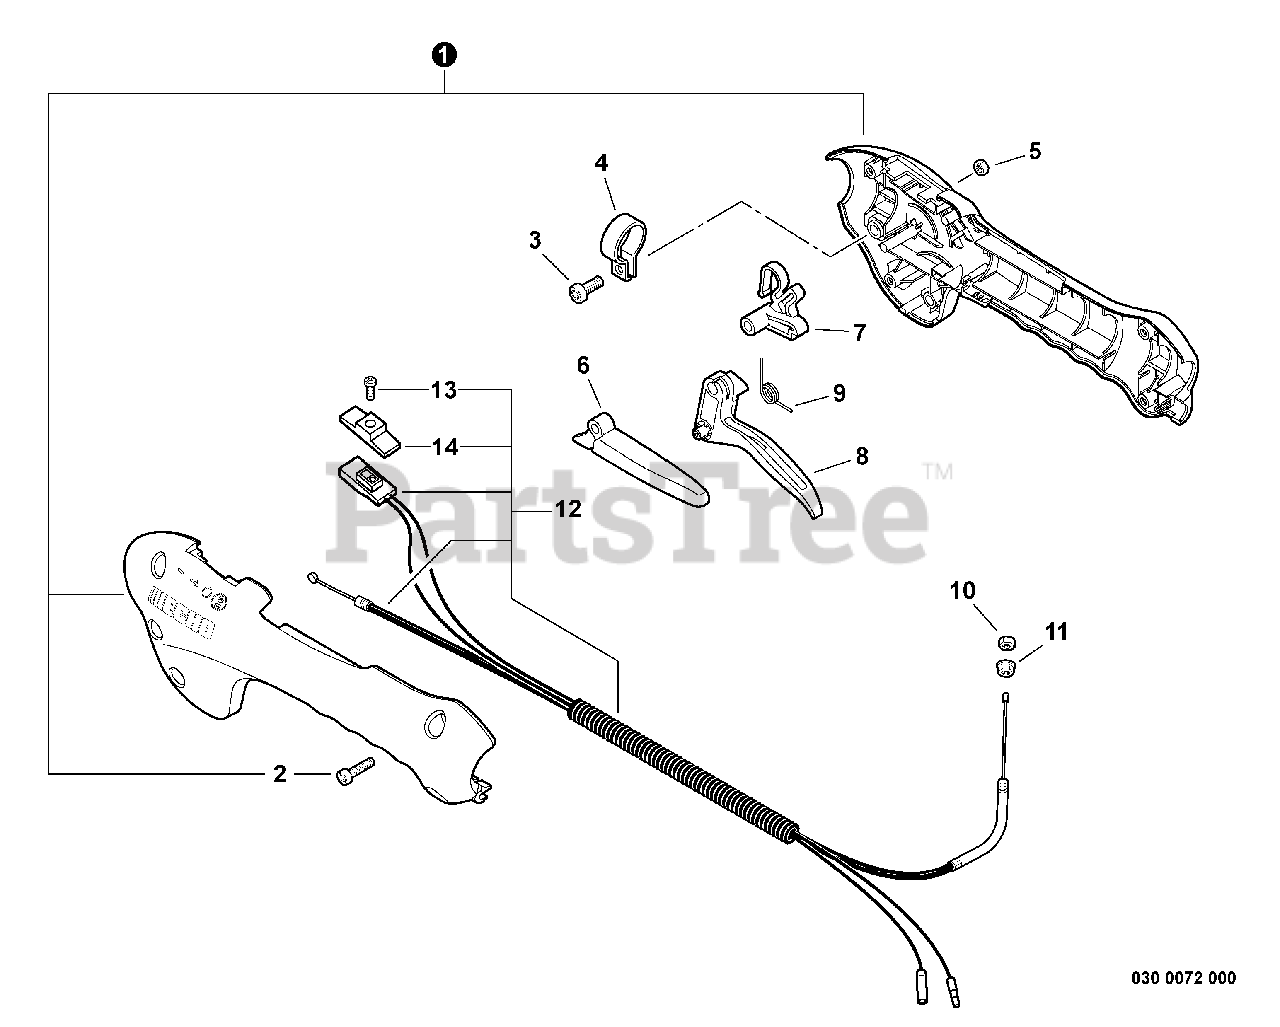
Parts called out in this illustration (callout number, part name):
1	CONTROL HANDLE ASSY
2	SCREW - 4X16 -- TAPPING
3	SCREW - 5X16
6	LEVER, TRIGGER LOCKOUT
7	LOCKOUT, THROTTLE
8	TRIGGER, THROTTLE
9	SPRING, TRIGGER
11	NUT - 6 -- FLANGE
12	CONTROL CABLE ASSY
13	SCREW - 3X10
14	KNOB, SWITCH - ORANGE
